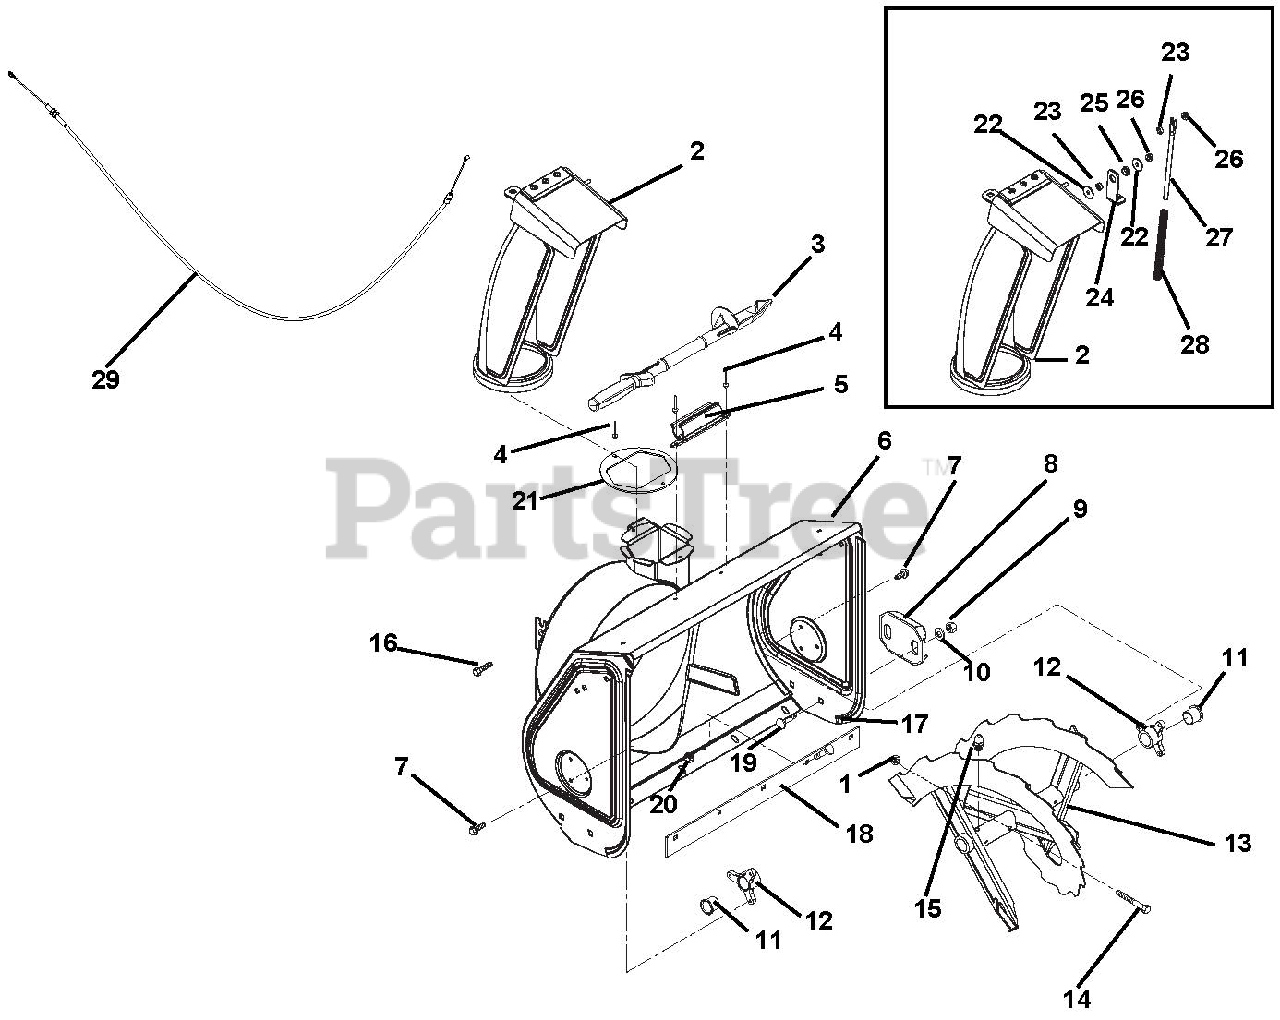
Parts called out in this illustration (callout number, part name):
1	@NUT-LK-CTR .25-20 YWZC
2	CHUTE, DISCHARGE W/REM.CAP,DEC
3	DEVICE, SNOW CLEAN OUT
4	RVT-POP .187 YZ
5	MOUNT, SNOW CLEAN OUT
6	BLOWER HOUSING, 24" HI ORANGE
7	SCR-TAP .25-20X.50 HWH TR YWZ
8	SKID SHOE, REVERSIBLE - ORANGE
9	@NUT-LK-CTR .38-16 YWZC
10	@WSHR-FL-STL.38X.875X.083 YWZC
11	BSHG-FLG SPLIT NYLINER .75"ID
12	BUSHING, RAKE SHAFT .75"
13	RAKE, 24" RH, BLK SERR W/ZERK
13	RAKE, 24" LH, BLK SERR W/ZERK
14	SHEAR BOLT WITH NUT
15	ZERK,FITTING .25X.125 DRIVE IN
16	@SCR-TAP .31-18X.50 HWH TR YWZ
17	BLT,RDSHHDSQSHNK .31-18X.62 YZ
18	SCRAPER BLADE, 24" COMPACT HI
19	@BLT-RHDSSQNK .38-16X.75 G5YZ
20	@NUT-LK-TOP-FLG .31-18 YWZC
21	BAFFLE, COMPACT DISCHARGE
22	WSHR-FL-STL .281X1.000X.063
23	BSHG-SLV .265X.500X.219
24	BRACKET, CABLE ANCHOR
25	BUSHING, POLYLINER-.50 SNAPIN
26	@NUT-LK-TOP-FLG .25-20 YWZC
27	ROD, DEFLECTOR CAP
28	SG-COMP .08X.40X6.50 14#/IN
29	CABLE, DEFLECTOR-COMPACT
